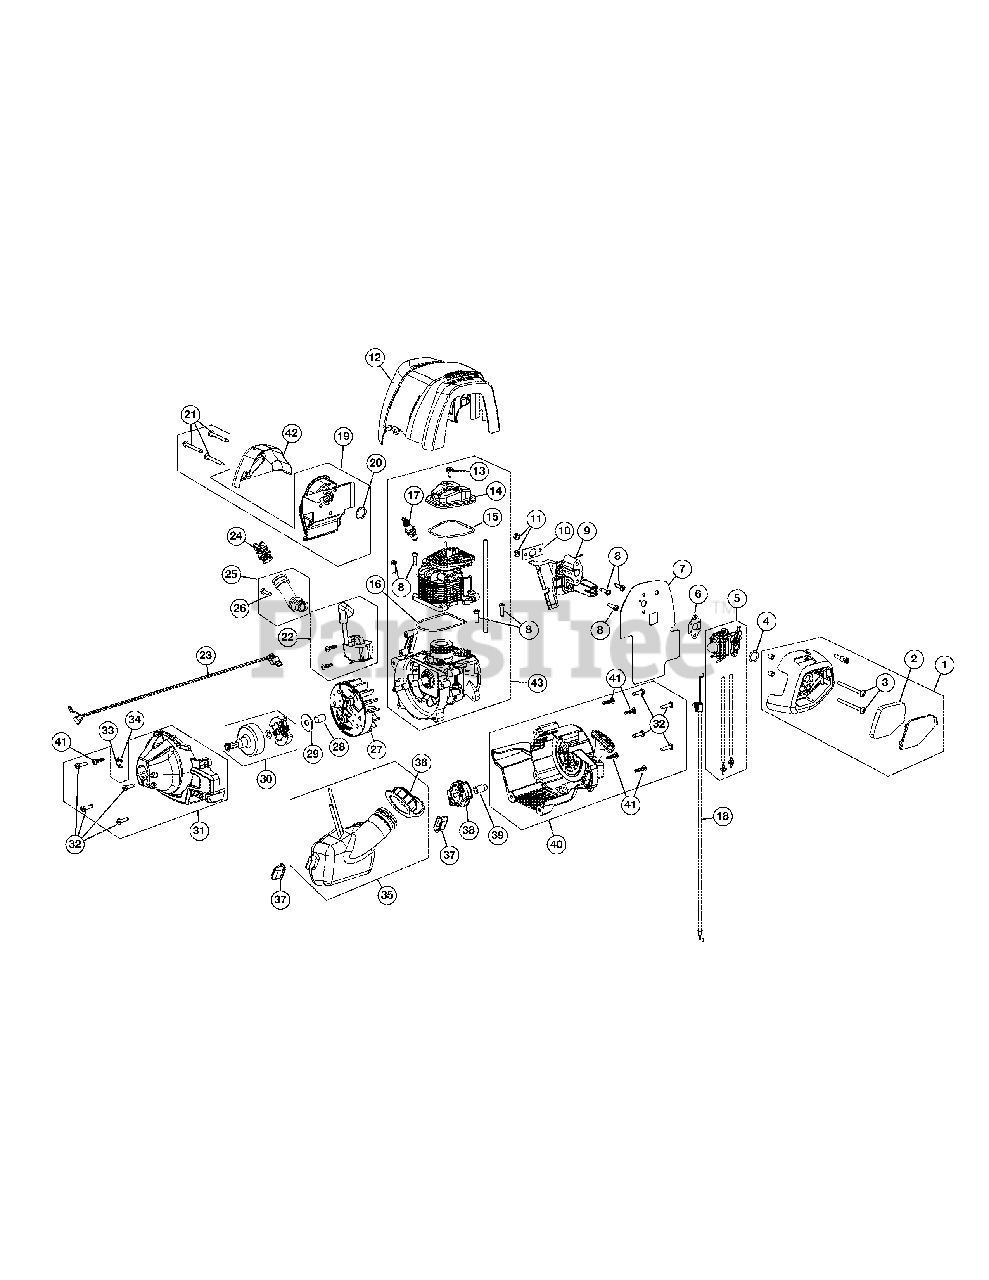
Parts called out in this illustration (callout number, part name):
1	Aircleaner Assembly
2	Air Filter
4	Carburetor O-Ring
5	Carburetor Assembly
6	Carburetor Gasket
7	Carburetor Baffle
8	Screw
9	Insulator
10	Insulator Gasket
12	Engine Cover
14	Valve Cover
15	Valve O-Ring
16	Cylinder O-Ring
17	Spark Plug
18	Throttle Cable
19	Muffler Assembly
20	Muffler Gasket
21	Muffler Bolt
22	Module Assembly
23	Lead Wires
24	Oil Plug Assembly
25	Oil Fill Tube Assembly
26	Tube Screw
27	Flywheel
28	Spacer
29	Clutch Washer
30	Clutch Assembly
31	Clutch Cover Assembly
32	Cover Screw
33	Anti-rotation Screw
34	Clamp Screw & Nut
35	Fuel Tank
36	Fuel Cap
37	Fuel Tank Pad
38	Pawl Assembly
39	Electric Start Adapter
40	Starter Cover Assembly
41	Starter Screw
42	Muffler Shield
43	Short Block Assembly
